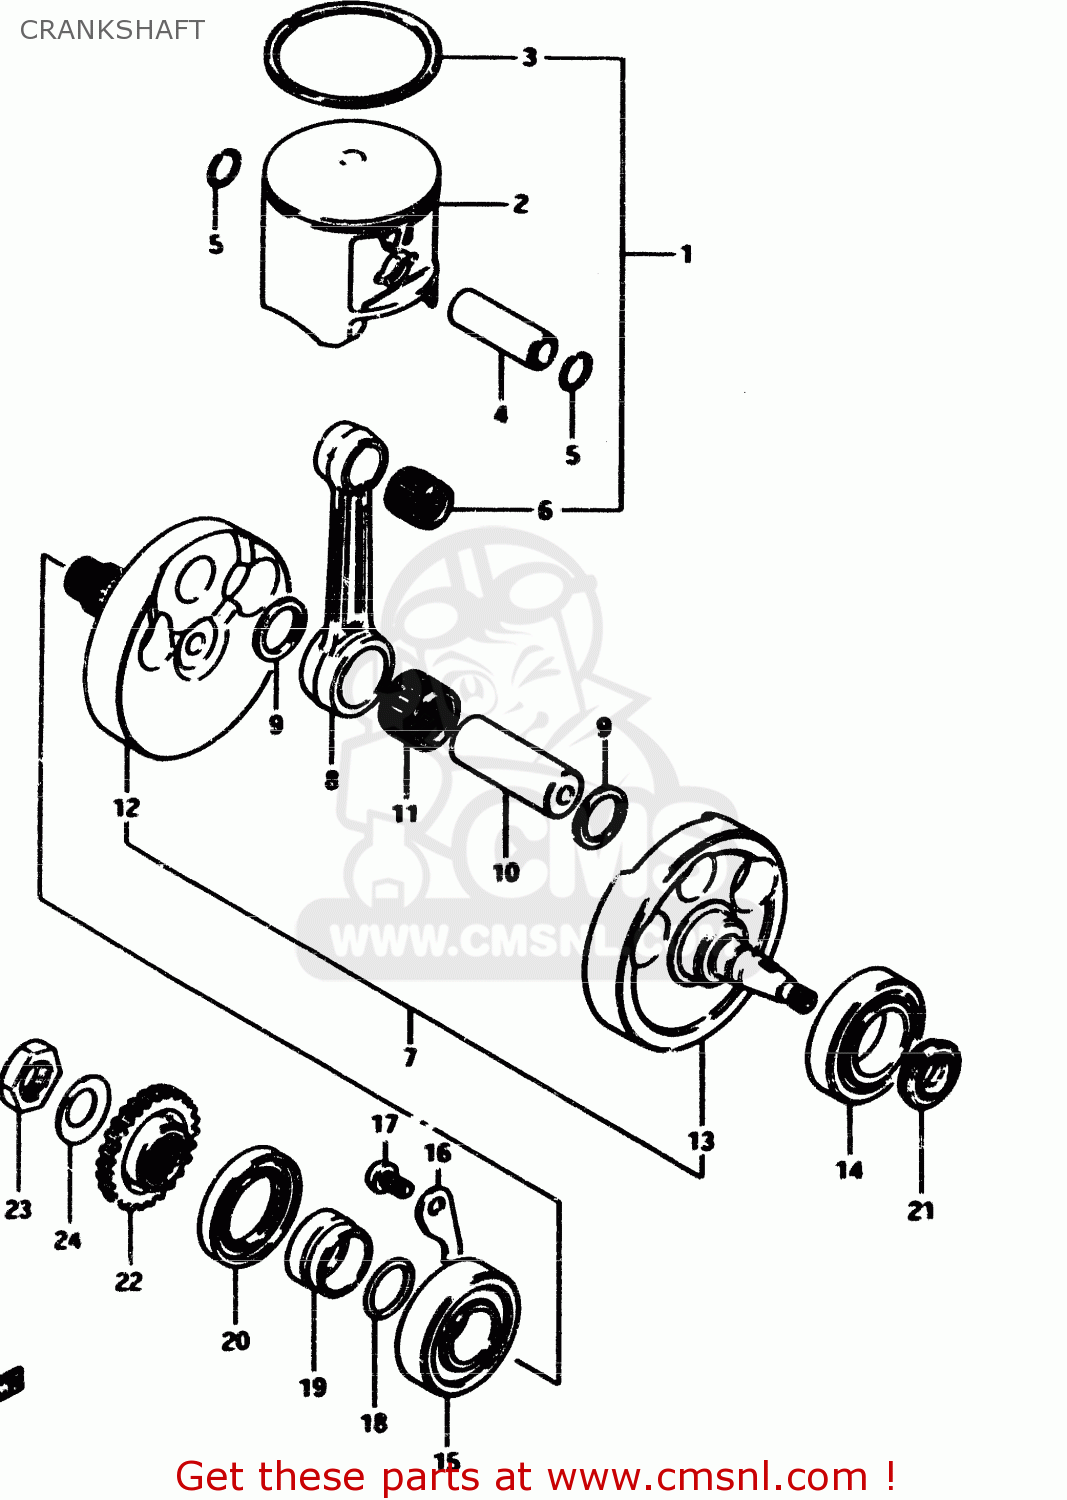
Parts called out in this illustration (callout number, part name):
1	PISTON SET (RM500F)
2	PISTON
3	RING,PISTON
4	PIN,PISTON (18MM)
5	CIRCLIP,PISTON PIN
6	BEARING(18X23X22)
7	CRANKSHAFT ASSEMBLY
8	ROD,CONNECTING
9	WASHER(26X32X1.5)
10	PIN,CRANK
11	ROLLER BEARING (26X33X2
12	CRANKSHAFT,RIGHT
13	CRANKSHAFT,LEFT
14	BEARING
15	BEARING
16	PLATE,CRANKSHAFT OIL S
17	SCREW
18	O RING(D:2.4,ID:27.7)
19	SPACER,PRIMARY DRIVE GEAR
20	SEAL,OIL(37X62X9)
21	SEAL,OIL(19.6X37X8)
22	GEAR,PRIMARY DRIVE
23	NUT (20MM)
24	WASHER
